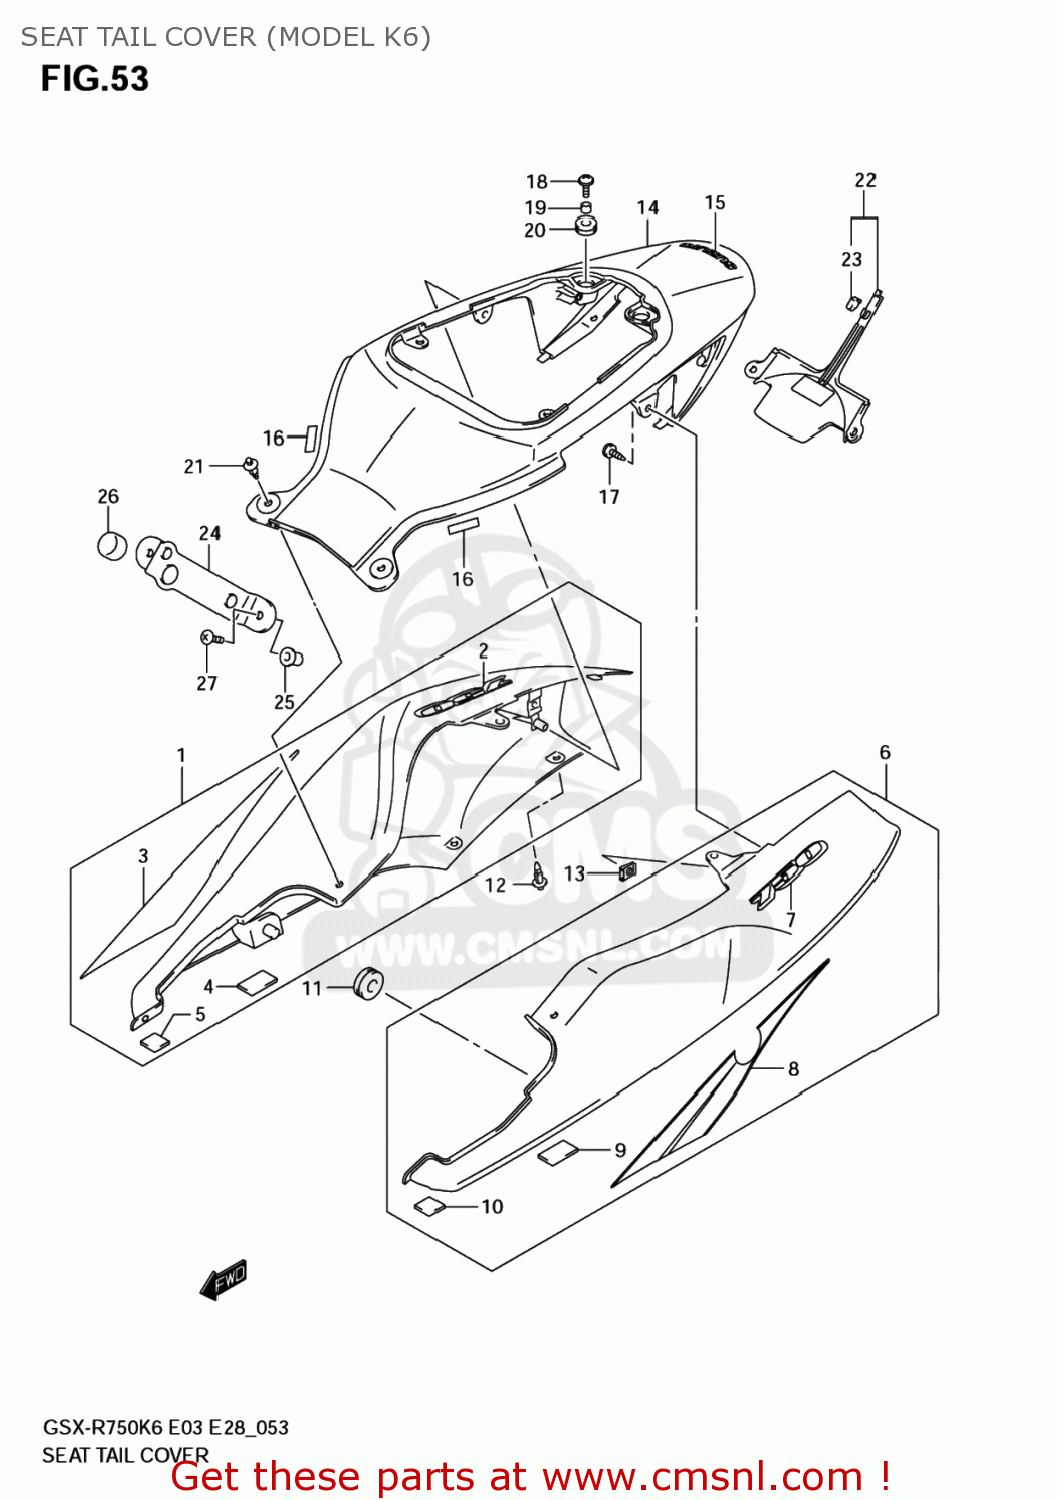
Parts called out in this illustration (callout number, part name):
1	COVER,SEAT TAIL,R(RED)
2	EMBLEM,750,R
3	TAPE,SEAT TAIL COVER,R
4	CUSHION,SEAT TAIL COVER LWR RR
5	CUSHION,SEAT TAIL COVER LWR FR
6	COVER,SEAT TAI
7	EMBLEM,750,L
8	TAPE,SEAT TAIL COVER,L
9	CUSHION,SEAT TAIL COVER LWR RR
10	CUSHION,SEAT TAIL COVER LWR FR
11	CUSHION
12	CLIP(BLACK)
13	NUT
14	COVER,SEAT TAI
15	EMBLEM,SUZUKI
16	TAPE(6X25X0.13)
17	SCREW
18	BOLT(6X20)
19	SPACER (6.5X10
20	CUSHION
21	CLIP(BLACK)
22	COVER,SEAT TAI
23	CUSHION,SEAT TAIL COVER RR
24	BRACKET,SEAT TAIL COVER
25	NUT
26	CUSHION
27	SCREW
